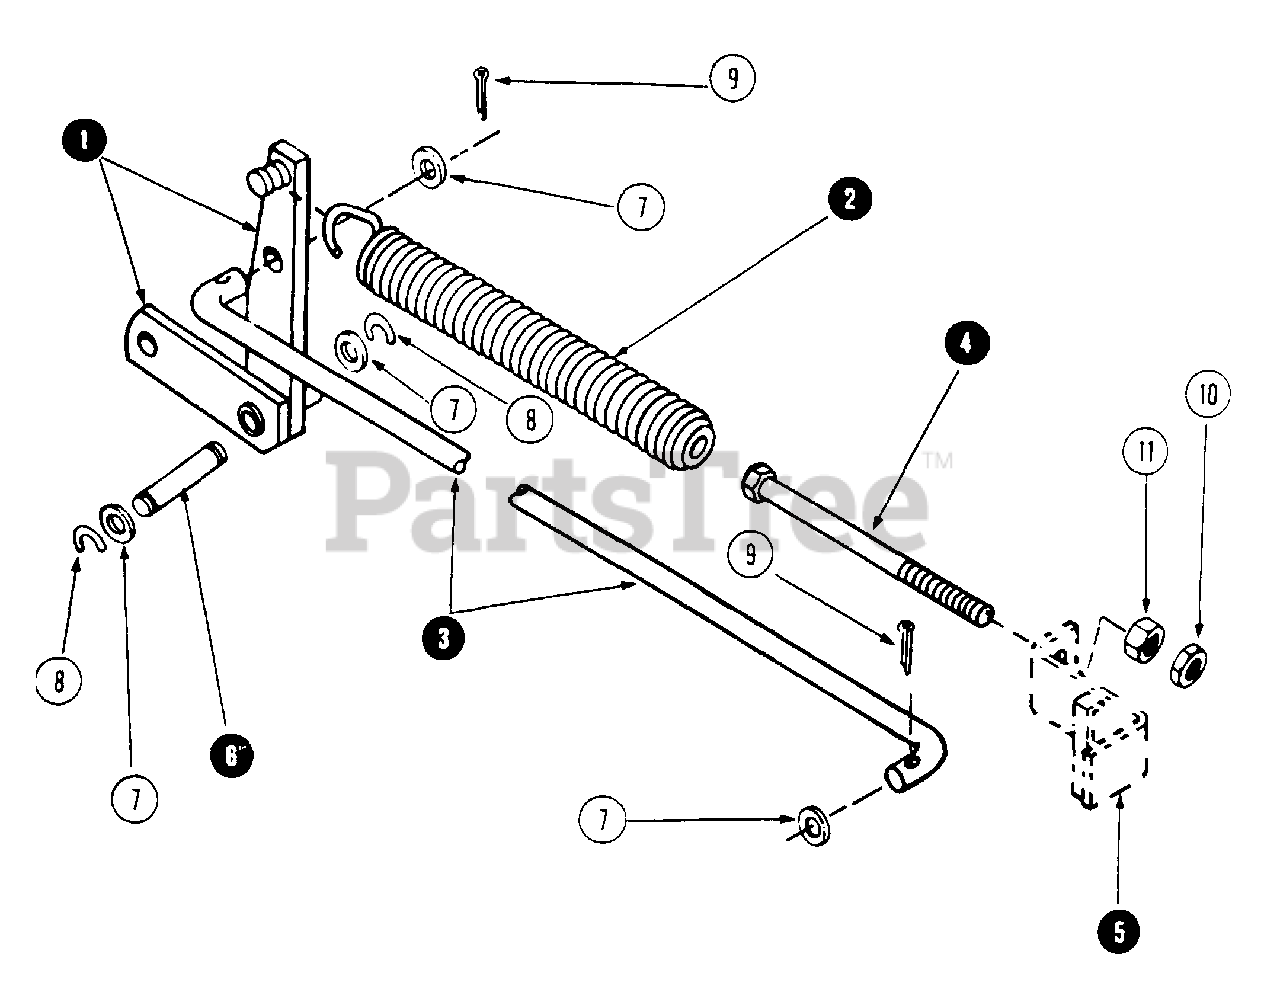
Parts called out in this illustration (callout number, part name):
1	BRACKET, ROCKSHAFT
2	SPRING, LIFT ASSIST
3	ROD, HITCH ACTUATING
4	BOLT, 3/8C x 5 - 3/4 HEX HEAD
5	BRACKET
6	PIN, ROCKSHAFT TO FRAME
7	WASHER, 1/2 FLAT
8	RING, RETAINING
9	COTTER-PIN, 5/32 x 1
10	NUT, 3/8C HALF-HEX
11	NUT, 3/8C HEX
